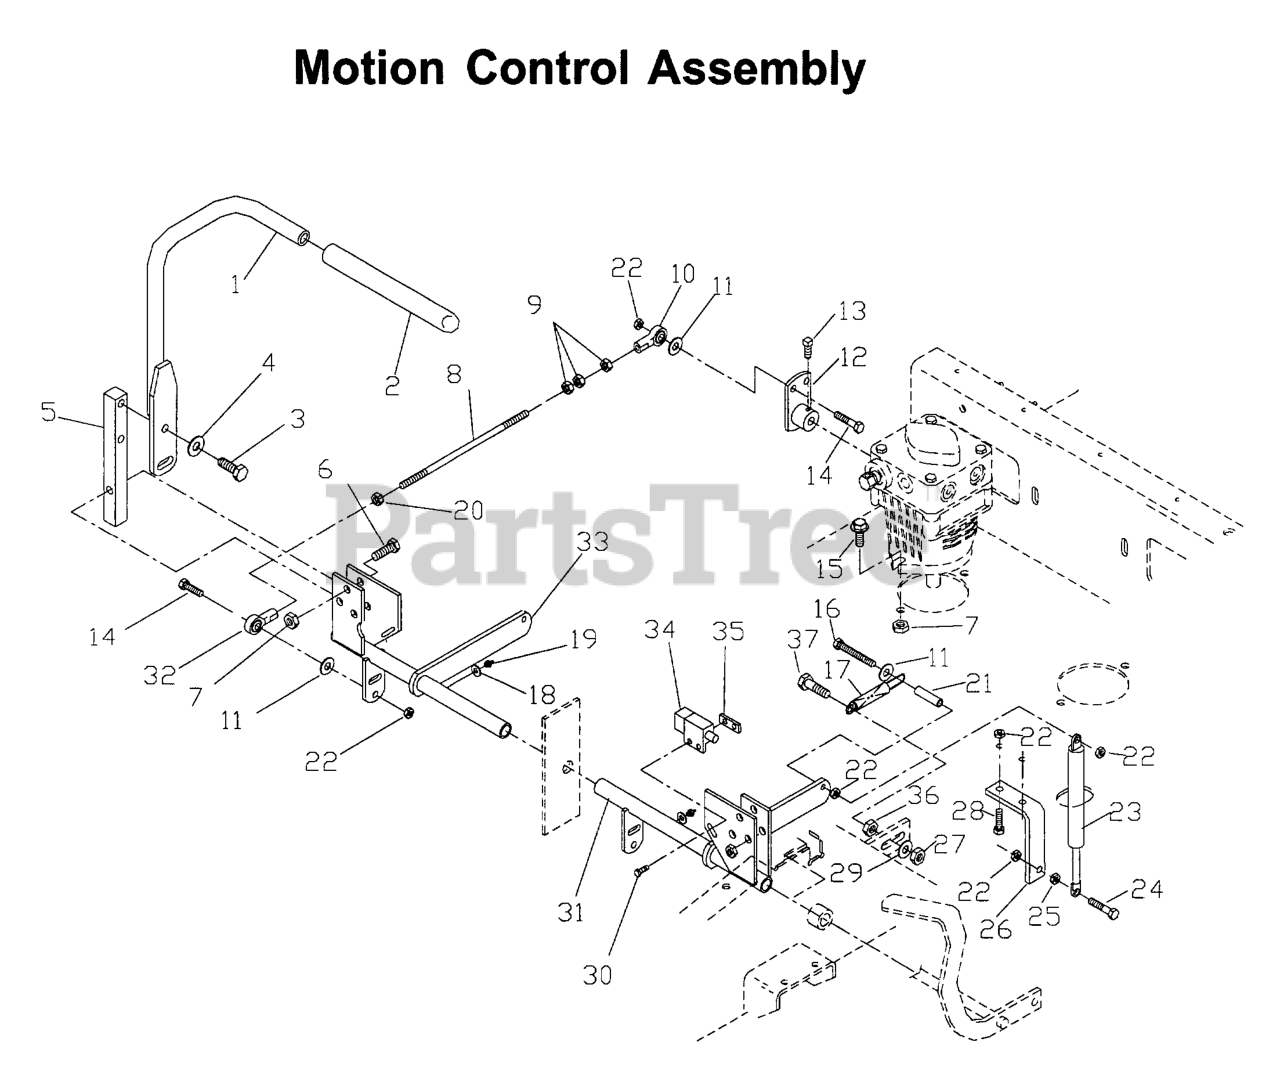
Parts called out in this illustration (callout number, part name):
1	CONTROL LEVER WELDMENT
3	HCS 3/8-16X1.GRD.5.ZD
4	WASHER, 3/8 DISC SPRING SPEC
5	CONTROL ARM
6	HCS 3/8C X 1 1/2
7	NUT 3/8C CENTERBLOCK
8	PUMP CONTROL LINK
10	BALL JOINT, RIGHT HANDED
11	WASHER 5/16 FLAT
12	PUMP LEVER
13	5/16C X 5/8 "V" POINT
14	HCS 5/16C X 1
15	4CS 3/8C X 1 SERRATED HEAD
16	TAP BOLT 5/16C X 2 1/4
19	ZERK
20	NUT 5/16F LEFTHAND
22	NUT 5/16C CENTERLOCK
24	HCS 5/16C X 1 1/4
25	NUT 5/16C WHIZ
26	BRACKET "I"
27	NUT 3/8-16 NYLOC
28	HCS 5/16C X 3/4
29	WASHER 3/8 FLAT
30	SCREW #10-24 X 5/8
31	CONTROL WELDMENT LT
32	BALL JOINT, LEFT HANDED
33	CONTROL WELDMENT RT.
34	SWITCH, INTERLOCK
35	TAPPED PLATE
36	NUT 3/8C WHIZ
37	HCS 3/8C X 2
